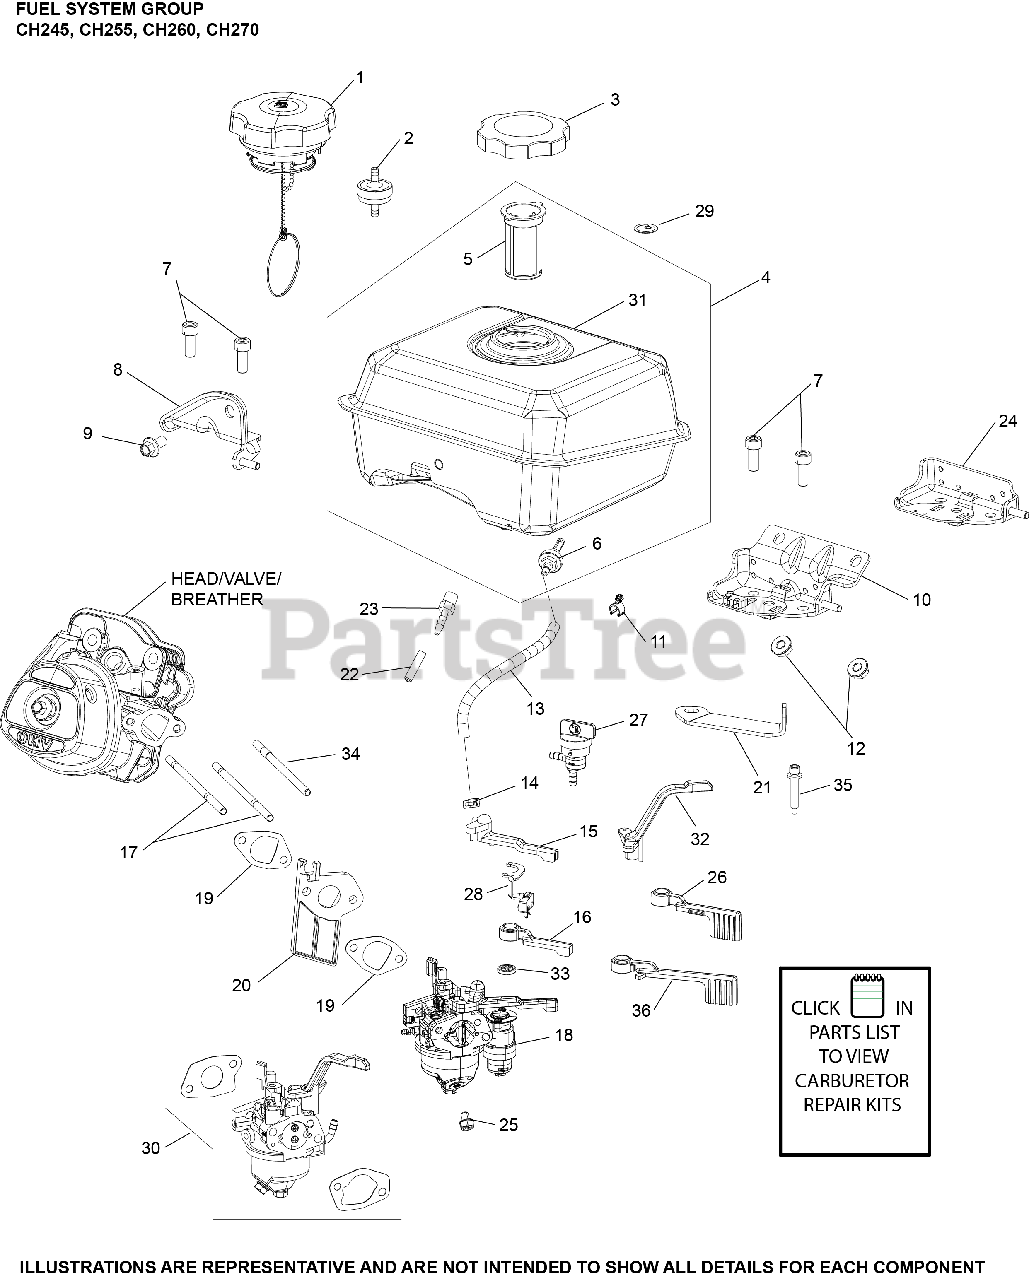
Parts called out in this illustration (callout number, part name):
3	CAP, FUEL TANK
4	TANK, ASSY FUEL
5	FILTER, FUEL TANK
6	FITTING, FUEL ASSY
7	SCREW, HEX SOCKET HD CAP (CKY)
8	BRACKET ASSY, FUEL TANK
9	SCREW, FLG 8X1.25X16
11	CLIP, FUEL HOSE
13	LINE, FUEL (10"-CUT TO LENGTH)
14	CLAMP, FUEL LINE
15	LEVER, CHOKE
16	LEVER, FUEL SHUTOFF
17	STUD, CARBURETOR
18	KIT, CARBURETOR ASSEMBLY
19	KIT, INTAKE GASKET
20	KIT, CARBURETOR INSULATOR
25	SCREW, BOWL DRAIN (CKY)
29	KIT, FUEL SCREEN
